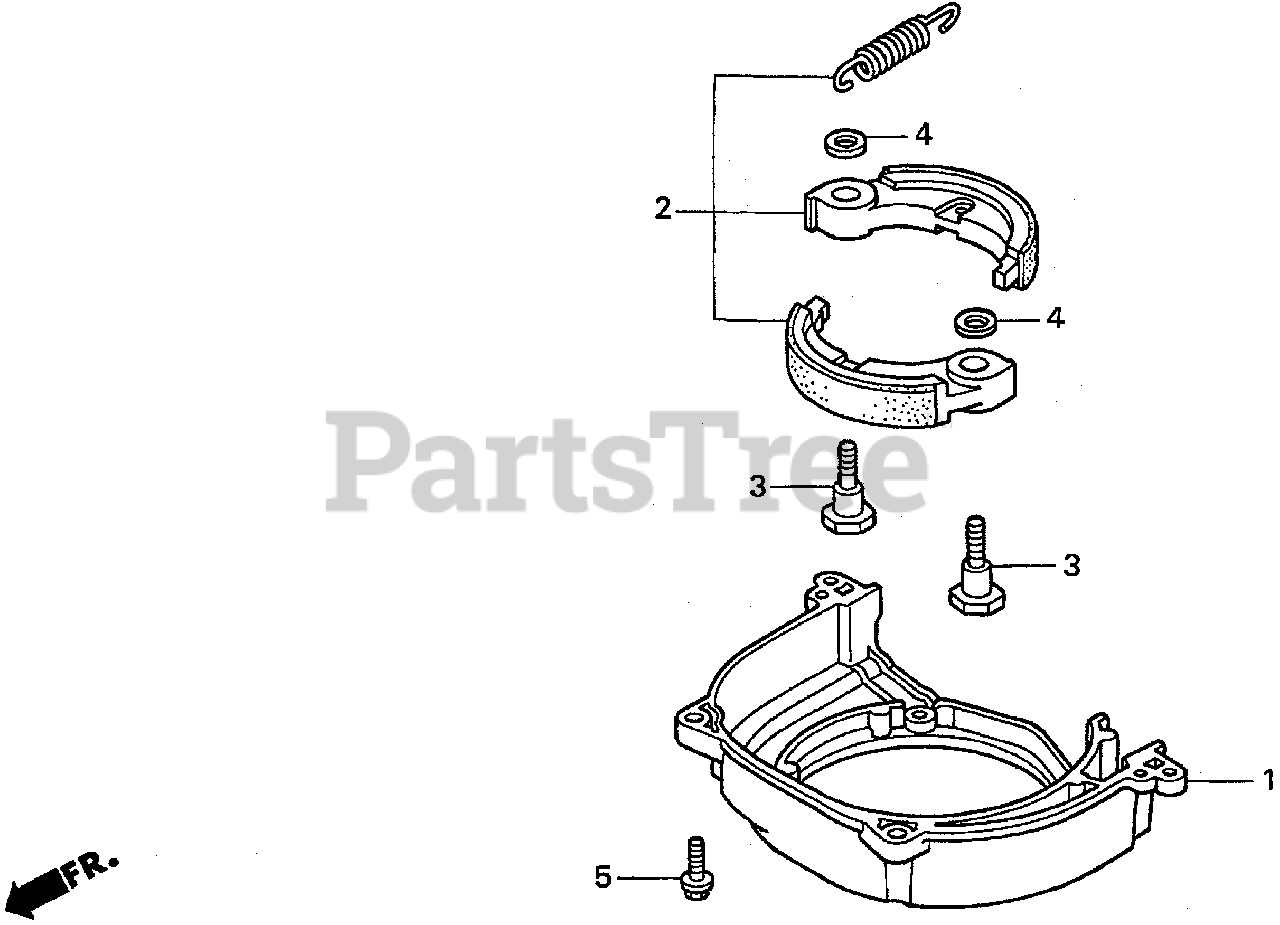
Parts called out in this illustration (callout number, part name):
1	COVER, FAN
2	CLUTCH ASSY.
3	BOLT, CLUTCH (6MM)
4	WASHER, CLUTCH (6X15)
5	BOLT, FLANGE (5X18)
